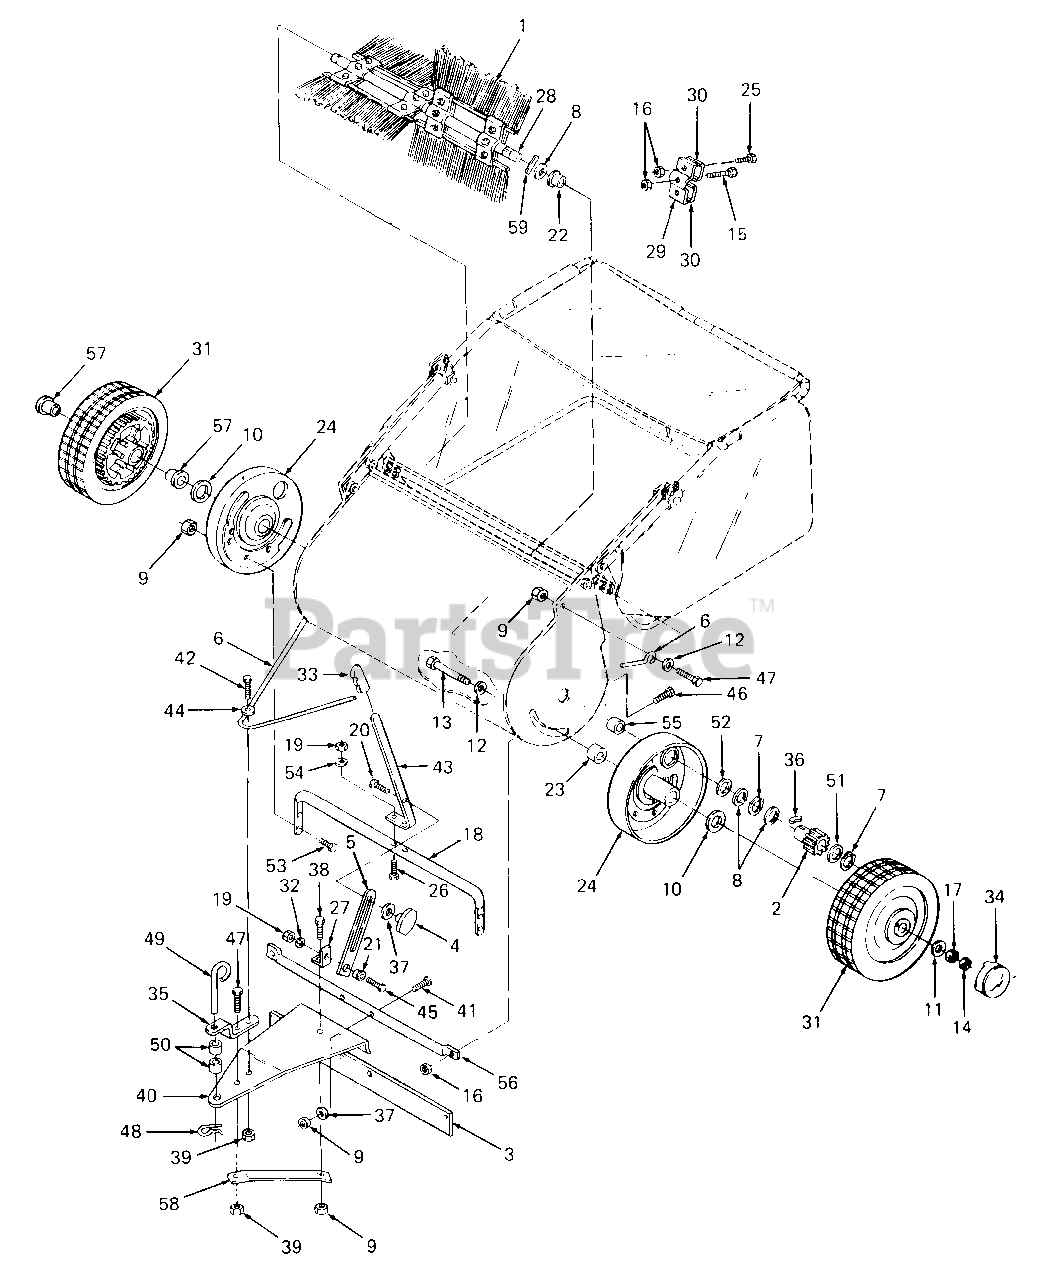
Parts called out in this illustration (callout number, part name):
1	Brush
2	Gear, Pinion LH
4	Knob, Height Adjustment
5	Strap, Height Adjustment
6	Rod, Brace
7	Ring, Retaining, .594 ID
8	Washer, Flat, .596 x 1.125 x .025
9	Nut, Hex Lock, 5/16-18 Thd
10	Washer, Flat, .783 ID x 1.125 x .025
11	Washer, Flat, .38 x 1.25
12	Washer, Std, 3/8
13	Bolt, Hex, 3/8-24 x 3-1/4 Lg
14	Nut, Jam, 3/8-24 Thd
15	Bolt, Hex, 1/4-20 x 1 Lg
16	Nut, Hex Lock, 1/4-20 Thd
17	Nut, Hex Lock, 3/8-24 Thd
18	Tube, Height Adjustment
19	Nut, Hex, 5/16-18 Thd
20	Bolt, Carriage, 5/16-18 x 3/4 Lg
21	Spacer, Bushing
22	Bushing, Brush Shaft
23	Spacer, .39 ID x 1-1/4 OD
24	Cover, Dust
25	Bolt, Hex, 1/4-20 x .75 Lg GR5
26	Bolt, Curved Hd, 5/16-18 x 1-5/8
27	Bracket, Angle
28	Shaft, Brush
29	Retainer, Brush (Double)
30	Retainer, Brush (Single)
31	Wheel Assy, Complete
32	Washer, Lock, 5/16 ID
34	Hub Cap
36	Pawl
37	Washer, Flat, Std, 5/16
38	Bolt, Hex, 5/16-18 x 3/4 Lg
39	Nut, Hex Lock, 3/8-16 Thd
40	Tongue, Hitch
41	Bolt, Carriage, 5/16-18 x 1-1/2
42	Bolt, Hex, 3/8-16 x 1.5 Lg
43	Handle, Height Adjustment
44	Washer, Flat, 17/32 x 1-1/2
45	Bolt, Truss Hd, Slotted, 5/16-18 x 3/4
46	Bolt, Carriage, 1/4-20 x 5/8
47	Bolt, Hex, 3/8-16 x 1-1/4 Lg
48	Cotter, Hairpin, 5/32
49	Pin, Hitch
50	Tube, Hitch Adjustment
51	Washer, Flat, .596 x .859 x .025
52	Washer, Flat, .78 ID
53	Bolt, Hex, 5/16-18 x 1/2 Lg
54	Washer, Bowed
55	Spacer, .781 ID x 1-1/4 OD x .5 Lg
56	Tube, Hitch
57	Bearing, Wheel
58	Bracket, Tongue
59	Pin, Spring, 3/16 x 1
